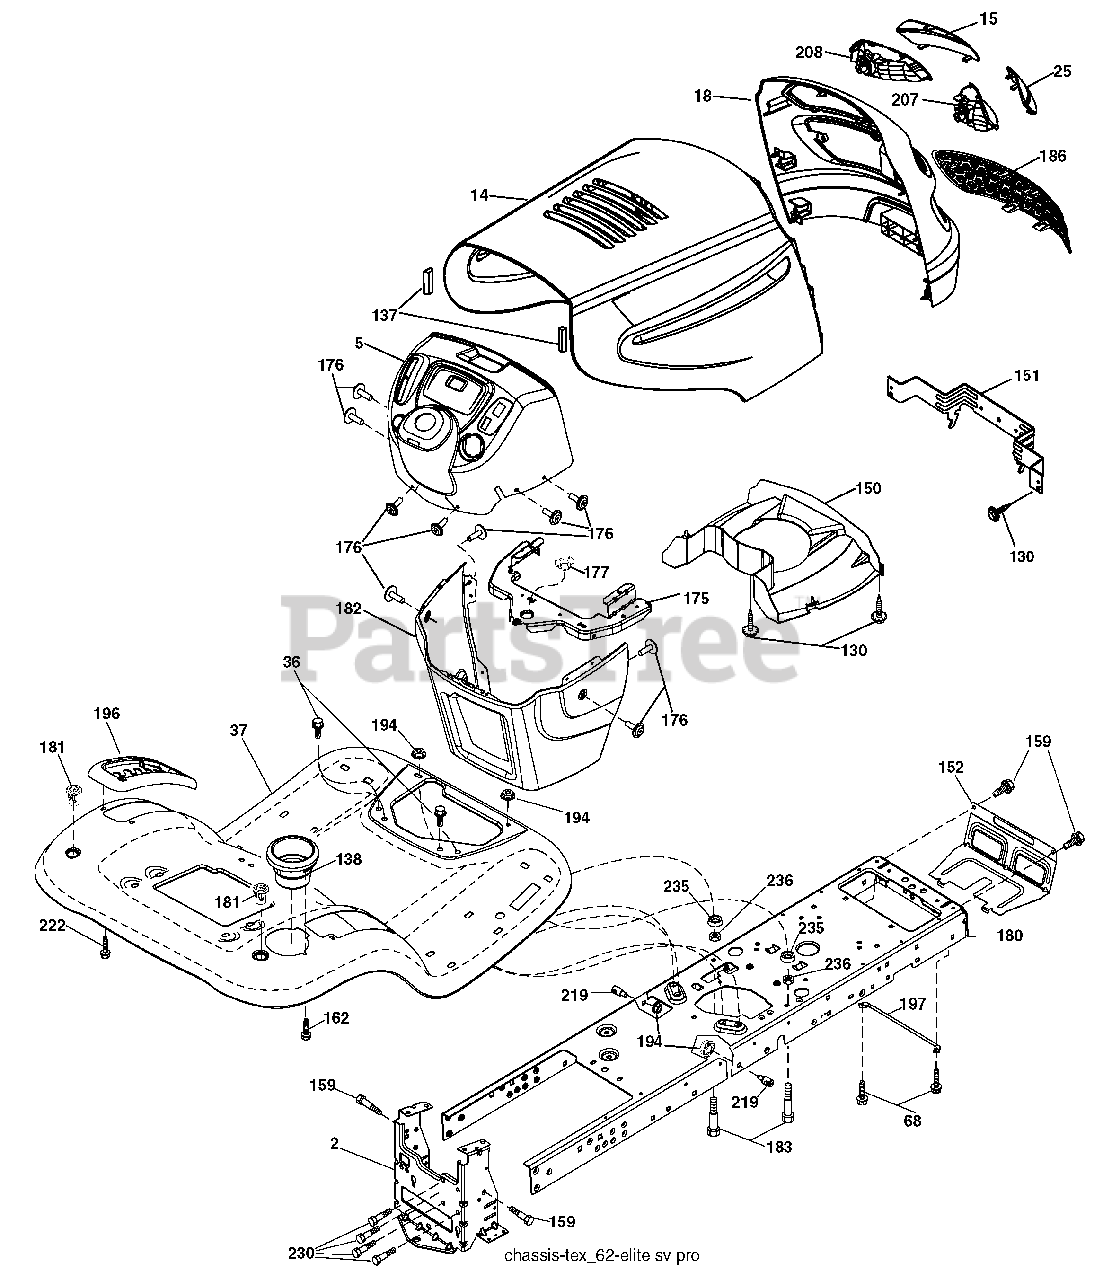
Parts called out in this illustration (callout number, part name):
2	Drawbar
5	Dash
14	Hood
15	Lens Grille LH
18	Grille
25	Lens Grille RH
36	Screw 5/16-18 x 3/4
68	Screw Thdrol 5/16-18 x 1/2
130	Screw 10 x 3/4 Single Lead-Hex
137	Bumper Hood
138	Cupholder
150	Duct Heat Hood
151	Bracket Pivot
152	Shield Browning/Debris
159	Screw Hexwsh Thdrol 3/8-16 x 3/4
162	Screw Hex Wsh Hi-Lo 1/4 x 1/2
175	Crossmember
176	Screw 10-24 x 5/8 Wshd Qdrx
177	Bushing Steering
181	Bushing Mtg. Fender Crgo.
182	Dash Lower
183	Bolt Fin Hex 5/16-18 x 1-1/4
194	Nut Lock Hex Flange 5/16-18
196	Console Asm. Deck Lift
197	Rod Pivot Hood
207	Bezel Grille RH
208	Bezel Grille LH
219	Stud Fastener
222	Screw Thd Roll 1/4-20 x 5/8
230	Bolt Shoulder 5/16-18
235	Spacer Fender
236	Nut center Lock 5/16-18
